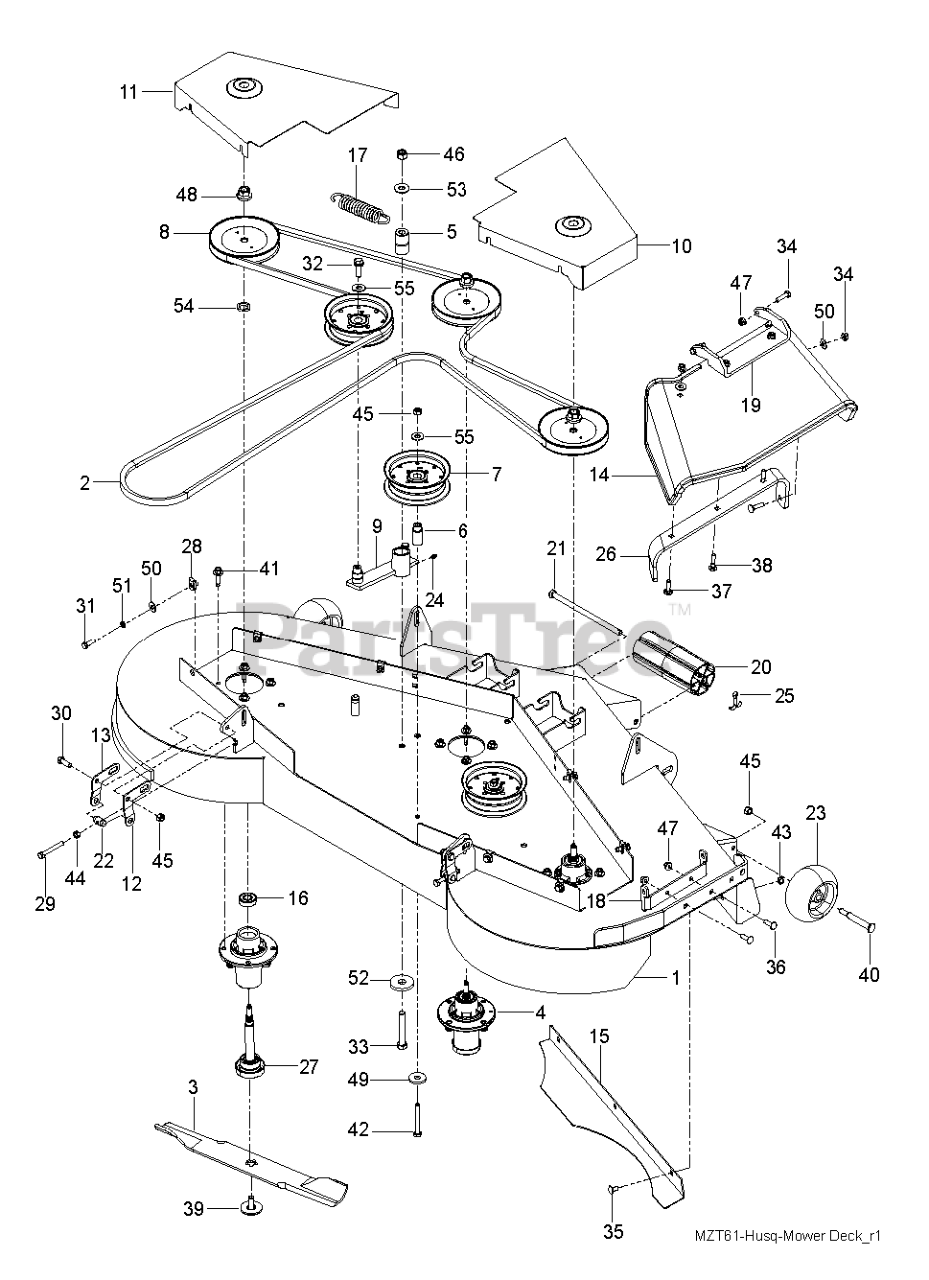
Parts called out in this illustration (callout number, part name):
1	DECK SVC MZT 61 W/DECALS ORG
2	BELT, DECK
3	BLADE, 21"
4	MANDREL ASM, CAST IRON
5	PIVOT BUSHING
6	IDLER BUSHING
7	PULLEY, IDLER
10	BELT SHIELD.RH.ORANGE
11	BELT SHIELD.LH. ORANGE
12	BRACKET.RT.PNT.MS431
13	BRACKET.LH.PNT.MS431
14	CHUTE, RUBBER DISCHARGE 52/61"
15	CONFINEMENT PLATE 61
18	BRACKET.M-ZT.CHUTE(ORG)
19	PIVOT BRACKET - CHUTE
20	NOSE ROLLER 48"
21	ROD.ROLLER.NOSE.NARROW.48"
22	TRUNION, PITCH
23	WHEEL GAGE DONUT
24	ZERK
25	COTTER PIN
26	BRKT, REINF - CHUTE 52/61"
27	SHAFT ASM MANDREL
28	U-CLIP 5/16-18 NUT RETAINER
29	HCS 5/16-18 X 2 1/2 TPBLT
30	HCS 3/8-16X1.GRD.5.ZD
31	HCS 5/16C X 3/4
32	4CS 3/8C X 1 SERRATED HEAD
33	HCS 1/2C X 3 1/4
34	BOLT.5/16-18X1-1/4 FULL.THREAD
35	CARRIAGE BOLT 5/16C X 5/8"
36	RHSSNB 5/16C X 1.0
37	BOLT, CARRIAGE 5/16X1-1/4
38	RHSNB 5/16-18 X 1-1/2 GR 5 ZD
39	BOLT.WASHER.ASM.7/16-2
40	BOLT, SHOULDER
41	BOLT.HEX.WASHR.HED.313-18X1.19
42	BOLT.HEX.WASHR.HED.313-18X1.19
43	NUT 5/16 NYLOC
44	NUT 5/16C HEX
45	NUT 3/8-16 NYLOC
46	NUT 1/2-13 HEX NYLOC ZD
47	5/16-18 NYLOC FLANGE NUT
48	NUT.FLANGE.LOCK.TOP
49	SPINDLE WASHER
50	WASHER 5/16 FLAT
51	WASH 5/16 DISC SPRING ZD
52	WASHER, SUPPORT
53	WASHER.9/16 X 1 3/8 X 12 GA.
54	WASHER.SPACER.MANDREL
55	WASHER 3/8 FLAT
